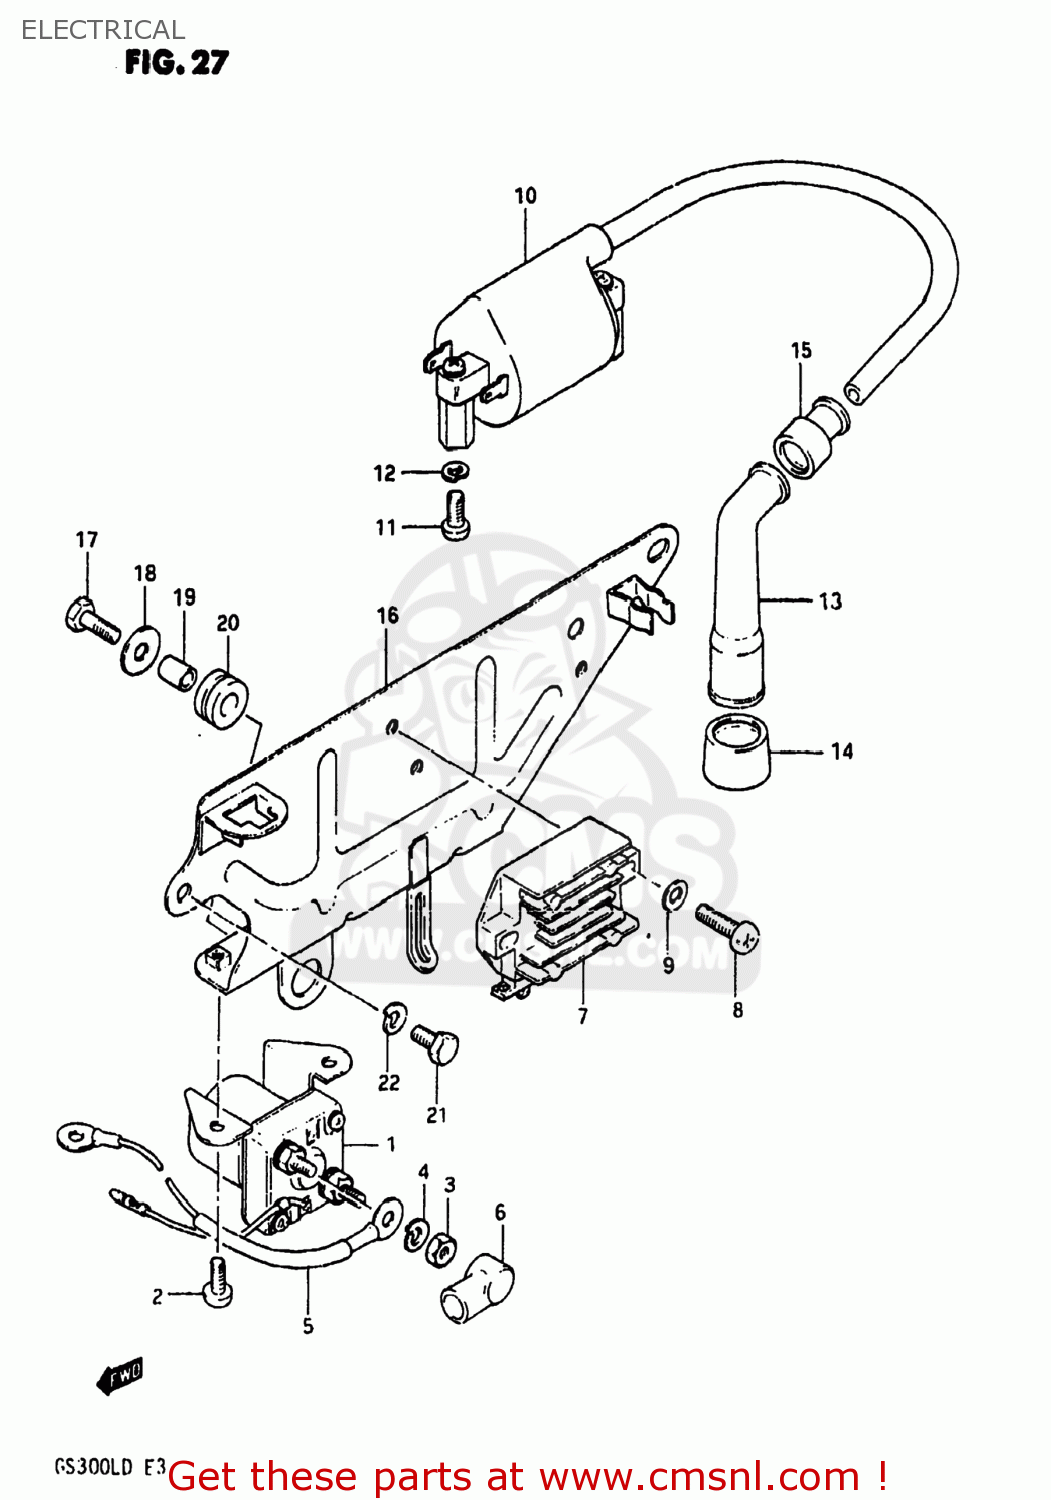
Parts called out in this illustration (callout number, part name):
1	RELAY ASSY,STARTING MOTOR
2	SCREW
3	NUT 6MM
4	LOCK WASHER
5	CORD,BATTERY MINUS
6	CAP,STARTER RELAY
7	RECTIFIER ASSEMBLY
8	SCREW
9	WASHER
10	COIL ASSEMBLY,IGNITION
11	SCREW
12	LOCK WASHER
13	CAP ASSY,SPARK PLUG
14	SEAL,SPARK PLUG
15	SEAL,SPARK PLU
16	HOLDER COMP,ELECTRONIC PARTS
17	BOLT
18	WASHER
19	SPACER (6.1X8X9.5)
20	CUSHION
21	BOLT
22	LOCK WASHER
